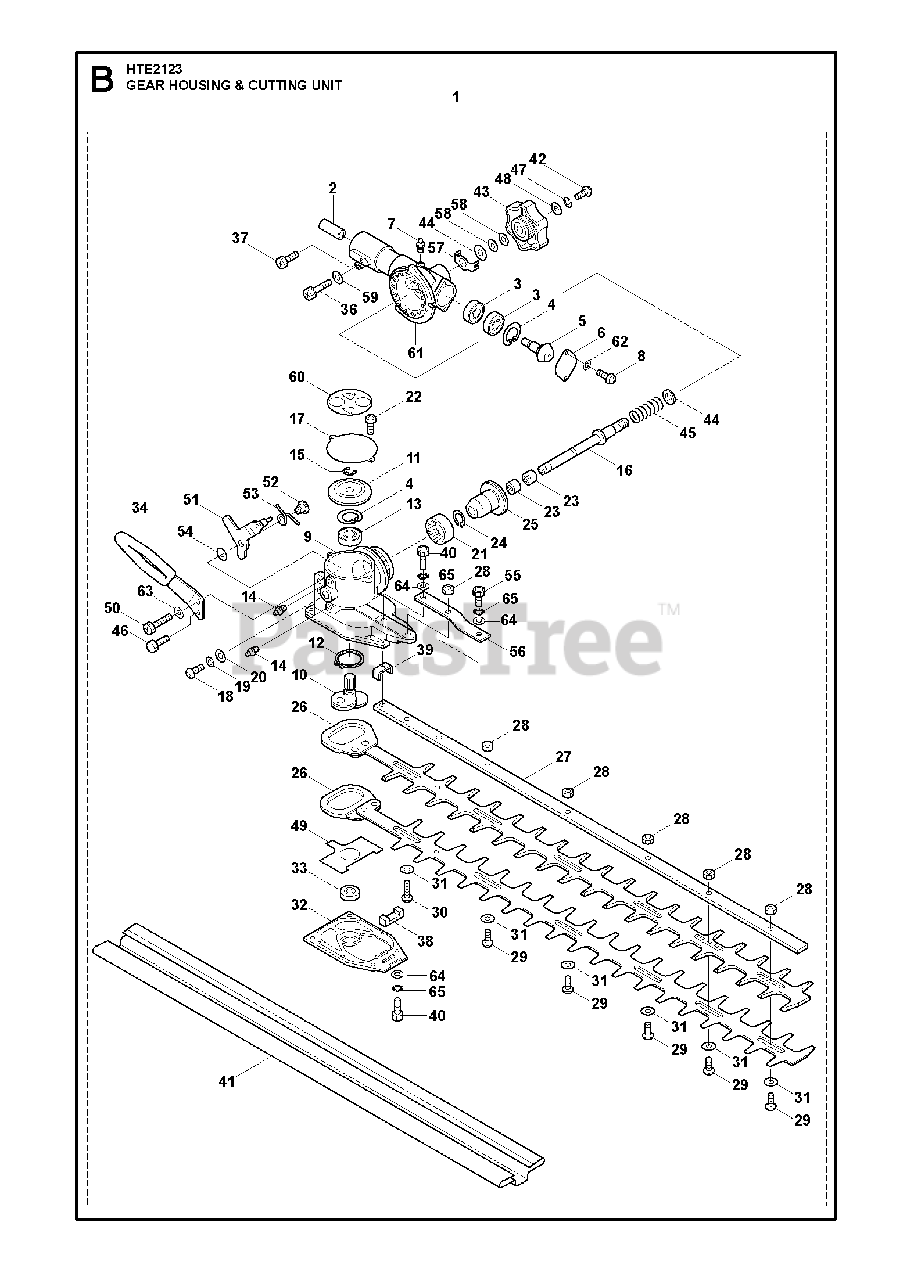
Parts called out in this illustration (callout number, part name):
3	BEARING
4	RETAINING RING SGH 26
7	GREASE NIPPLE
8	SCREW NLA
12	RETAINING RING
13	BEARING
14	GREASE NIPPLE
15	SNAP RING
19	SPRING WASHER 6.4
20	WASHER - M6
22	SCREW NLA
24	RETAINING RING
28	NUT FLANGE - M6
31	WASHER 6,4X18X1,5
33	BALL BEARING
36	BOLT
44	WASHER 6,4X18X1,5
46	SCREW
47	SPRING WASHER 6.4
48	WASHER - M6
50	SCREW
54	WASHER 6,4X18X1,5
55	SCREW MC6S 5X8
62	WASHER
63	SPRING WASHER 6.4
64	WASHER
65	SPRING WASHER 6.4
